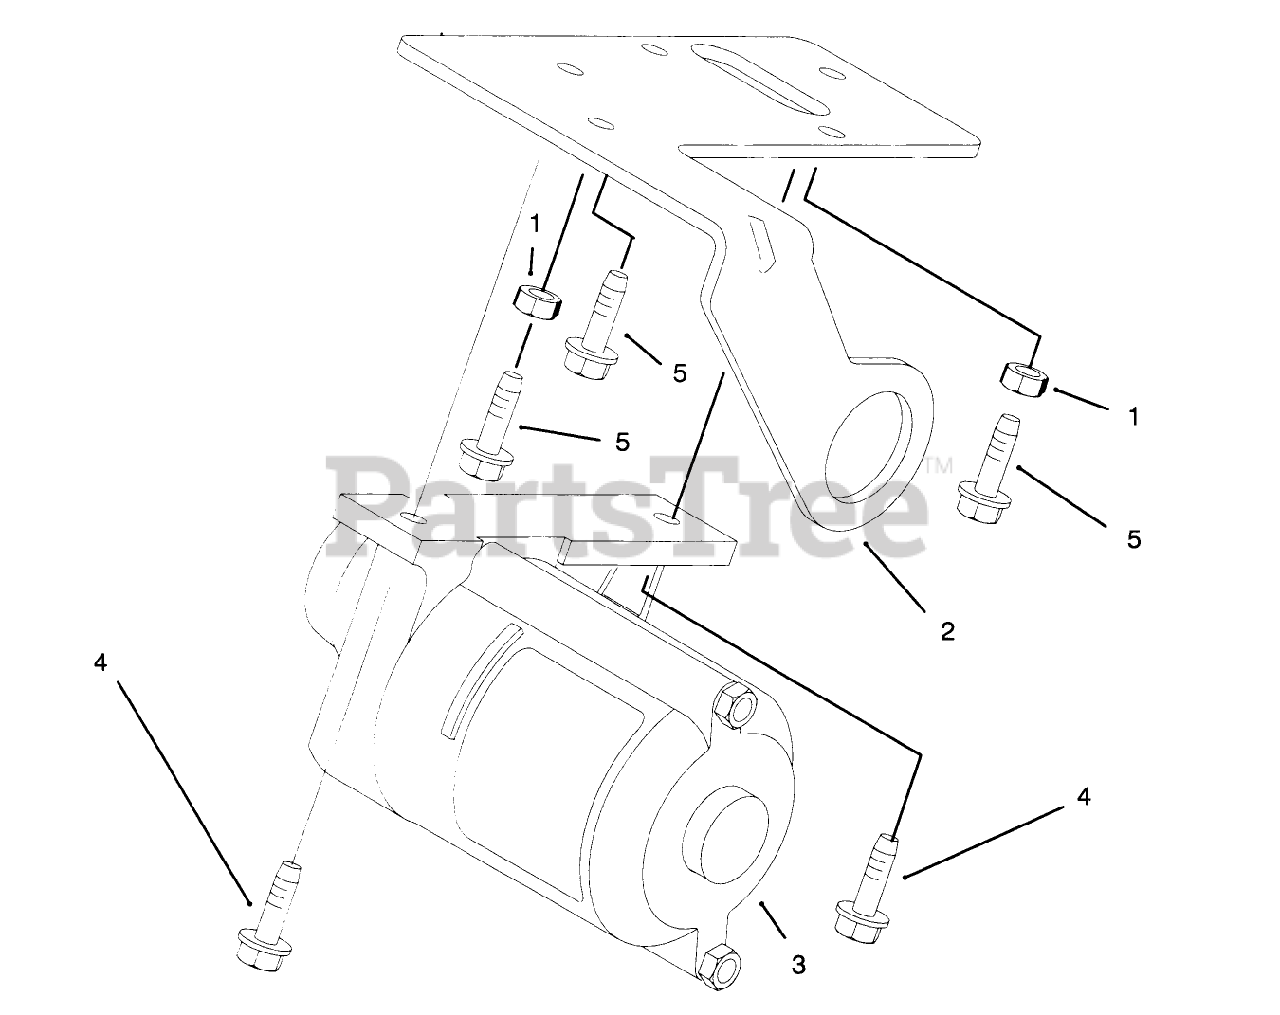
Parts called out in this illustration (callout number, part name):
1	NUT-LOCK, NI
2	MOUNTING BRACKET ASM
3	Motor-Starter
4	SCREW
5	Screw
